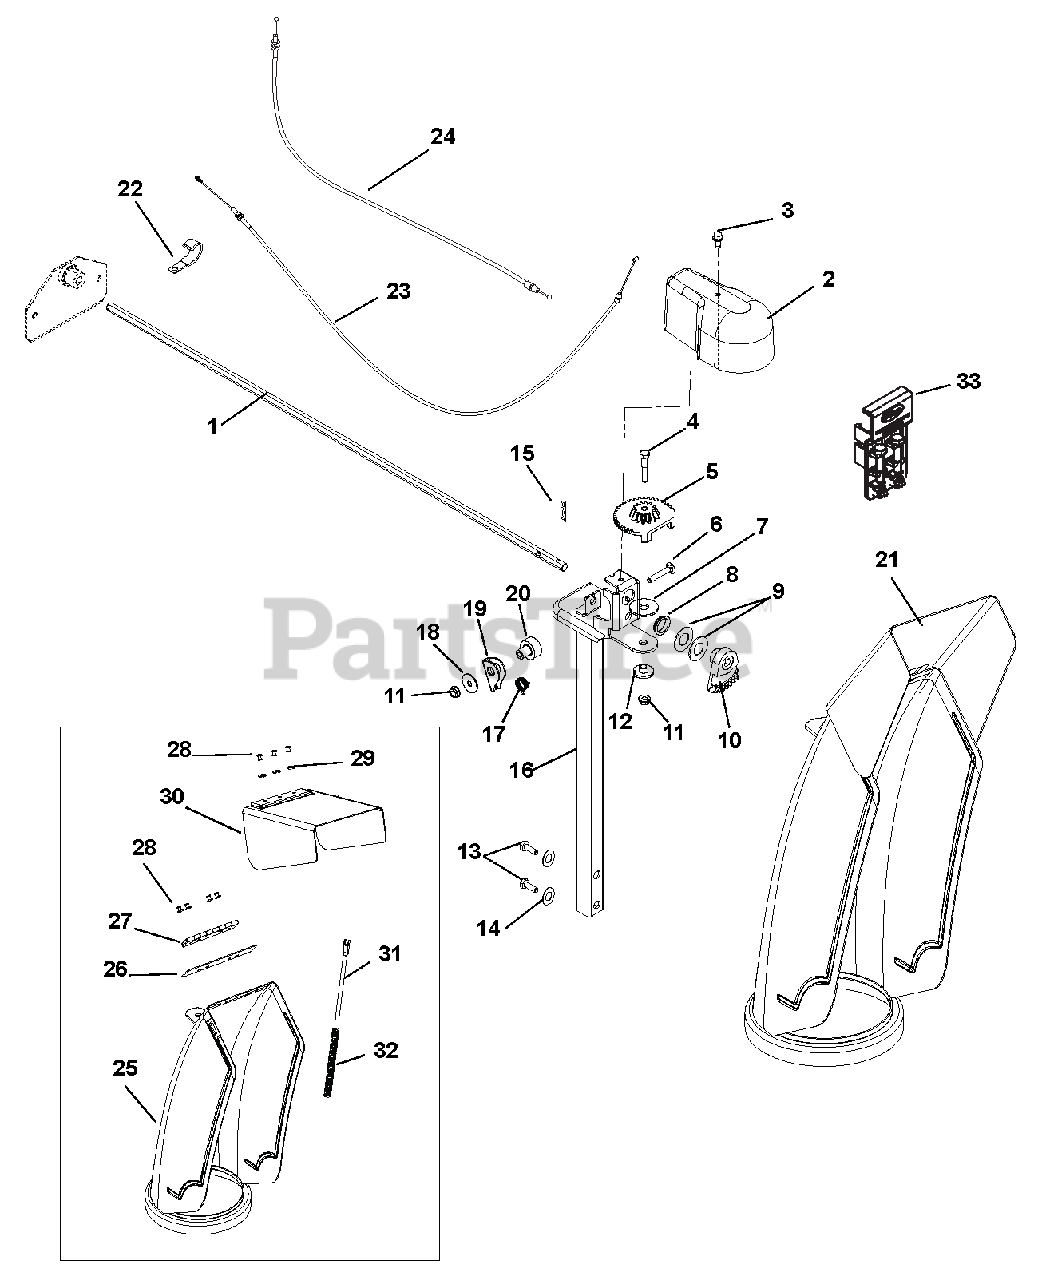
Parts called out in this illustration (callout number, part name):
1	ROD, HEX - CHUTE ROTATION
2	COVER, CHUTE GEAR
3	SCR-TAP .25-20X.50 LGHWH TR YZ
4	@BLT-HEX .25-20X1.50 GR5 YWZC
5	GEAR, CHUTE
6	@BLT-RDHDSQNK .25-20X1.50 G5YZ
7	WSHR-FLT-NYL .515X1.375X.093
8	BUSHING, POLYLINER-.75 SNAPIN
9	WSHR-FL-STL.754X1.125X.062YWZC
10	GEAR, CHUTE-ACTUATION
11	@NUT-LK-CTR-FLG .25-20 YWZC
12	BSHG-FLG .265X.477X.375X1.00
13	@BLT-HEX .38-16X1.75 GR5 YWZC
14	@WSHR-LK .38X.094 REG YWZC
15	PIN-HAIR INT .08X.18X1.18 YWZC
16	PEDESTAL, CHUTE - QUICK STICK
17	SG-TORS
18	WSHR-FL-STL .281X1.000X.063
19	ARM, LOCKING
20	BUSHING, LOCK ARM
21	CHUTE, DISCHARGE W/CAP & DECAL
22	J-CLAMP
23	CABLE, DEFLECTOR-COATED
24	CABLE, CHUTE LOCK
25	CHUTE, NOTCHED DISCHARGE
26	CAP SEAL 5.50
28	RVT-POP .187 YZ
29	WSHR-FL-STL .196X.500X.06 YZ
30	CAP, LARGE W/DECAL
31	ROD, DEFLECTOR CAP
32	SG-COMP .08X.40X6.50 14#/IN
33	HOLDER W LARGE SHEAR BOLT /NUT
